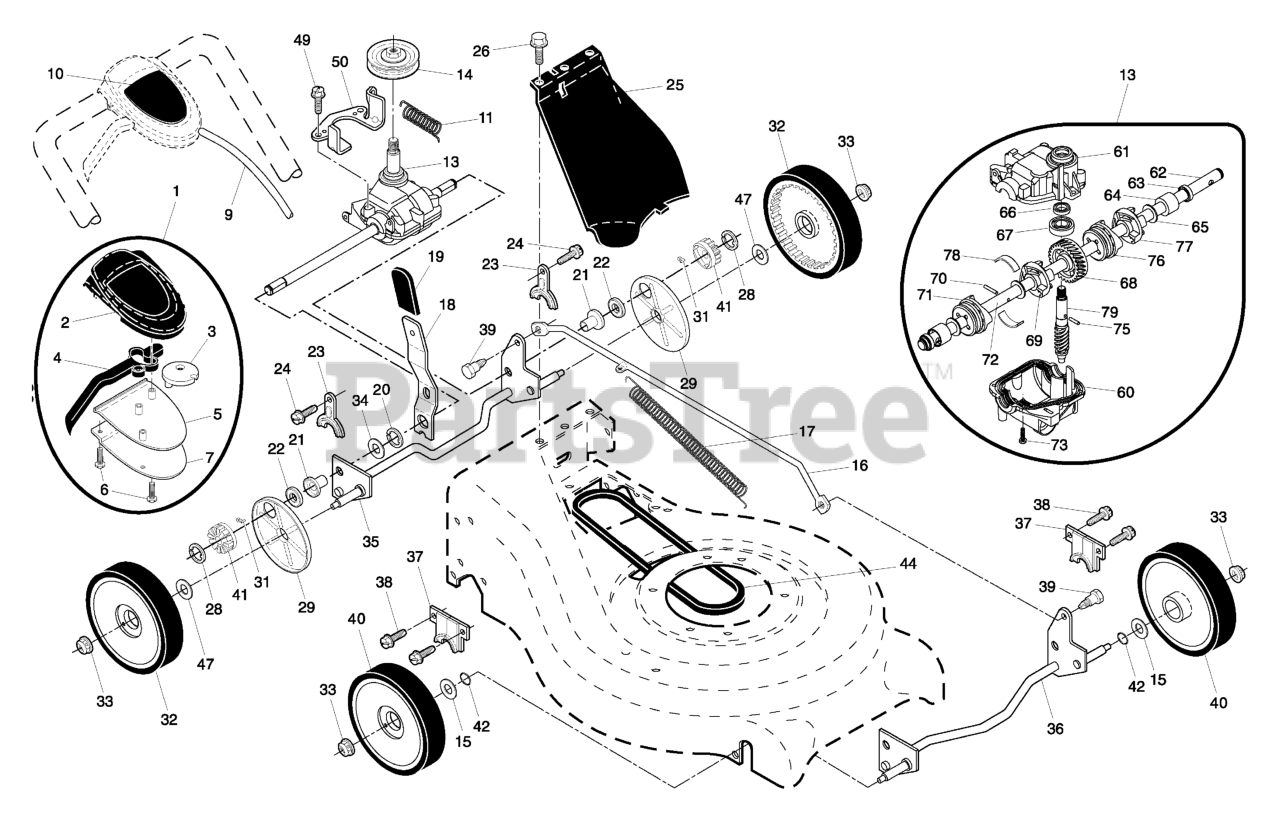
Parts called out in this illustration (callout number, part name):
1	DRIVE CONTROL ASSY, AUTO WALK
2	COVER TOP AUTO WALK CONTROL
3	PULLEY.CAM.DRIVE.CONTROL.EZ
4	LEVER, AUTOWALK DRIVE CONTROL
5	COVER BOTTOM AUTO WLK CONTROL
6	SCREW, PHILLIPS HEAD 10 X 5/8
7	BRACKET.DRIVE.CONTROL.MOUNT.BL
9	CABLE.ASSY.RGD.EZ.AUTO
10	DECAL, DRIVE
13	TRANSMISSION.21.RWGD.AUTO.SP
14	PULLEY.1.PIECE
15	WASHER.FLAT.1/2
16	ROD.CONNECTING.SPT.BLACK
17	SPRING
18	SPRING.SELECTOR.SPT.21
19	KNOB, SELECTOR SPRING
21	BEARING SUPPORT
22	BEARING
23	BRACKET
25	COVER.DRIVE.21.RWGD.MO
28	E-RING 7/16 RE
29	COVER.DUST.WHEEL
31	PAWL, DRIVE
32	WHEEL & TIRE ASSY, REAR
33	NUT.HEX.FLANGE.3/8-16.LO(3 2)
35	SHAFT ASSY REAR
36	SHAFT ASSY, FRONT
37	RETAINER.FRONT.SHAFT
39	SHOULDER BOLT SEMI GIMLET PT.
40	WHEEL & TIRES ASSY, FRONT
41	PINIION.14.TOOTH.RGD
42	O-RING..070X.487.NEOPRENE
44	BELT.RGD.VS
47	WASHER FLUT
50	BELT KEEPER
60	CASE UPPER
61	SHAFT OUTPUT LONG
62	SEAL.OUTPUT.SHAFT
65	SEAL INPUT SHAFT
67	GEAR 28 TEETH
68	DOG.FIXED.LH.32003
69	PIN 7 33732
70	DOG.MOVEABLE.LH.32005
71	SHAFT OUTPUT SHORT (12294)
73	CASE, LOWER
75	PIN 3.50.337 - 33733
76	DOG.FIXED.RH.32004
77	DOG.MOVEABLE.RH.32006
78	SPRING LEAF
79	SHAFT WORM
